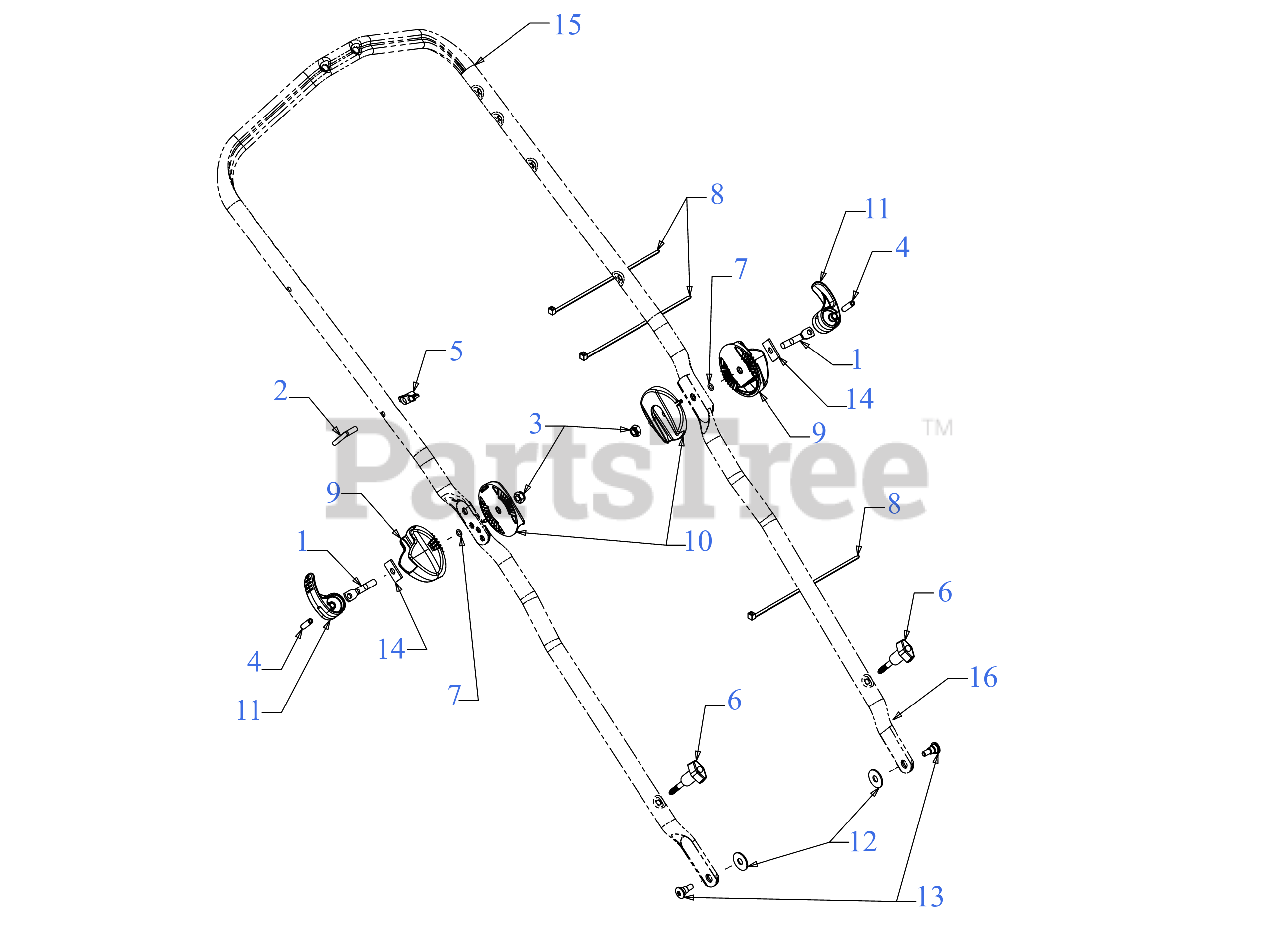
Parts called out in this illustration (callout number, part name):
1	EYE BOLT (M8-1.25" x 1.8")
2	EYEBOLT 1/4-20
3	HEX NUT
4	SPRING PIN 1/4 x 1.00
5	HANDLE KNOB
6	WING KNOB 1/4-20
7	O-RING 0.24" x 0.380" x 0.070"
8	7" CABLE TIE
9	PIVOT HANDLE ADJUSTMENT (OUTER)
10	PIVOT HANDLE ADJUSTMENT (INNER)
11	HEIGHT ADJUSTMENT LEVER (SBD GRAY)
12	FLAT WASHER 344X1.00
13	SHOULDER SCREW .450X .188X 1/4-20
14	CAM PLATE
15	UPPER HANDLE (ERGO XL) (POWDER BLACK)
16	LOWER HANDLE (EZ FOLD) (POWDER BLACK)
